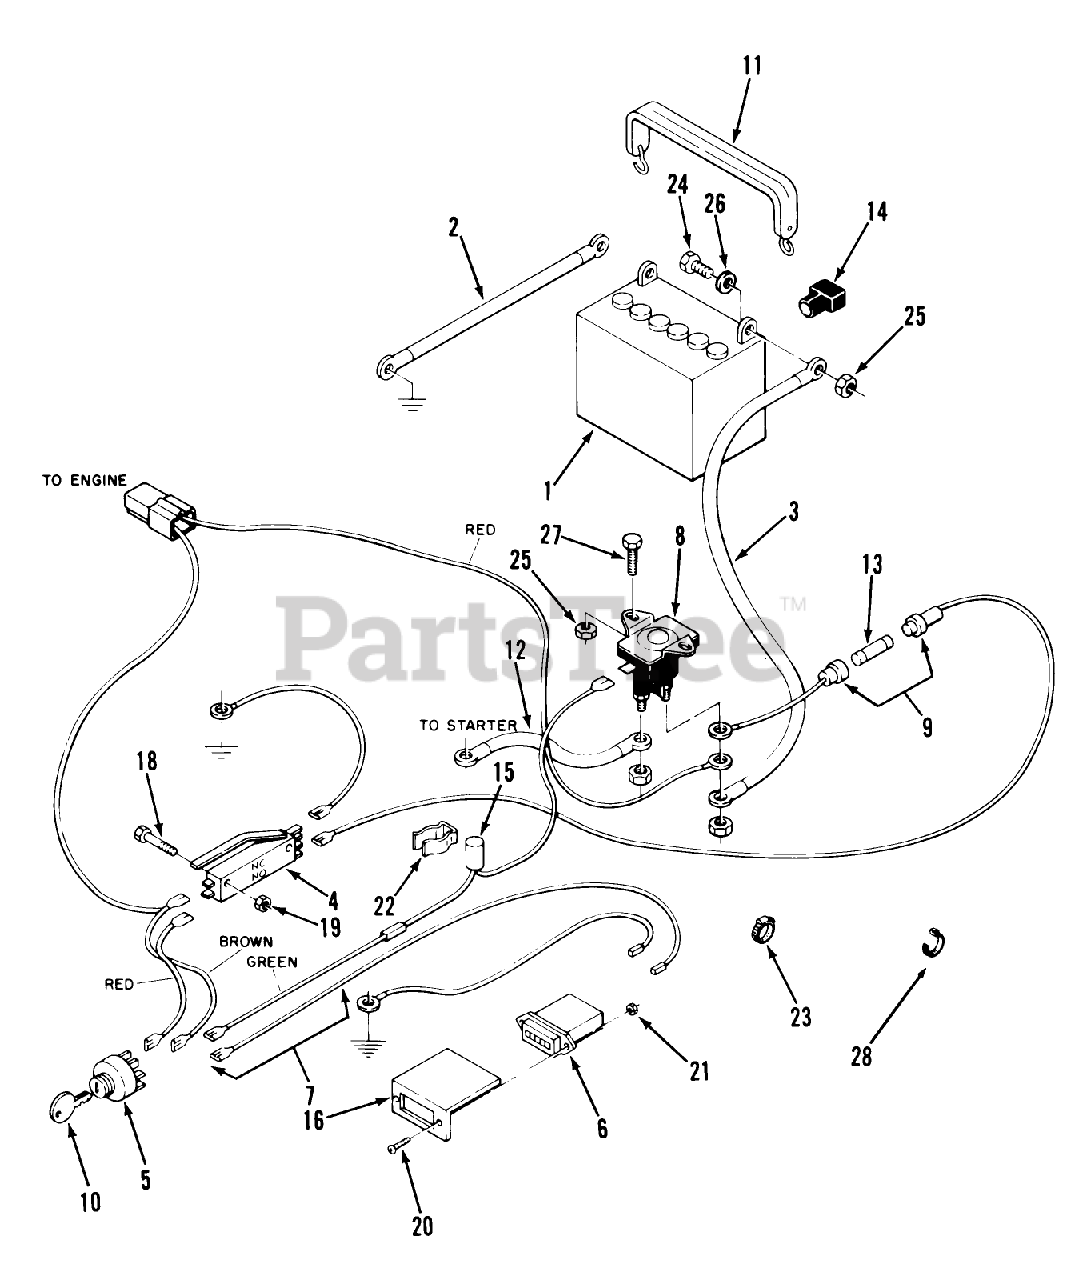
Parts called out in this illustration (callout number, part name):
4	SAFETY SWITCH
5	SWITCH ASSY
8	SOLENOID-STARTER
11	DISC-OBTAIN LOCALLY
